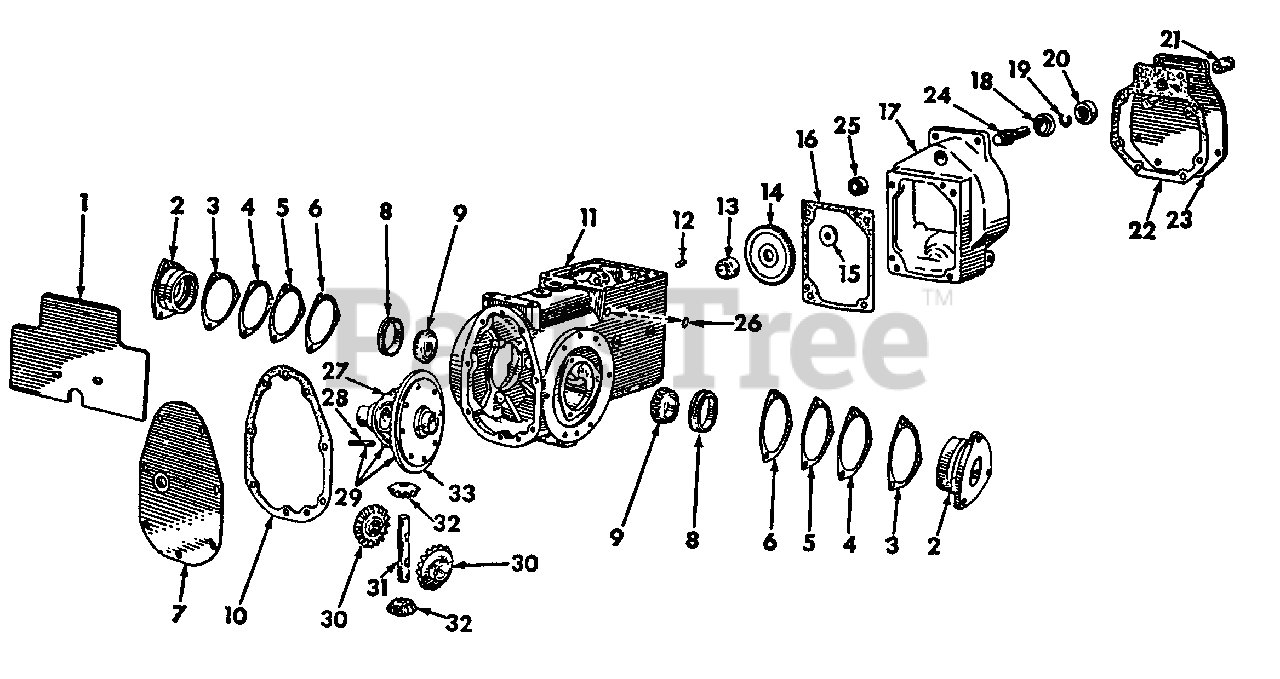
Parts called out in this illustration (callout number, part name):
1	Shield, Transmission Case Rear Cover
2	Cage w/Cup, IH-ST974 Differential Brg
3	Shim, Differential Brg Retainer, .004
4	Shim, Differential Brg Retainer, .007
5	Shim, Differential Brg Retainer, .0149
6	Shim, Differential Brg Retainer, .0299
7	Plate Assy, Transmission Case Rear Cover
8	Bearing, Differential Cup
9	Bearing Assy, Differential Cone
10	Gasket, Transmission Case Rear Cover Plate
11	Case Assy, Transmission
12	Dowel, Transmission Case to Reduction Housing
13	Spacer, Driven Reduction
14	Gear, Reduction Drive -84T
15	Retainer, Driven Reduction Gear
16	Gasket, Reduction Drive Housing
17	Housing, Reduction Drive
18	Bearing Assy, Reduction Drive Shaft Front Ball
19	Ring, Reduction Drive Shaft Brg Ext Snap
20	Seal, Reduction Drive Shaft Oil
21	Coupling, Clutch Shaft
22	Gasket, Reduction Housing Cover Plate
23	Plate Assy, Reduction Housing Cover
24	Shaft, Reduction Drive
25	Bearing Assy, Reduction Drive Shaft Rear
26	Plug, 11/16 Expansion
27	Case, Differential
28	Pin, Differential Pinion Shaft Lock
29	Case Assy, Differential
30	Gear, Differential Side
31	Shaft, Differential Pinion
32	Pinion, Differential -10T
33	Gear, Differential Drive -46T
